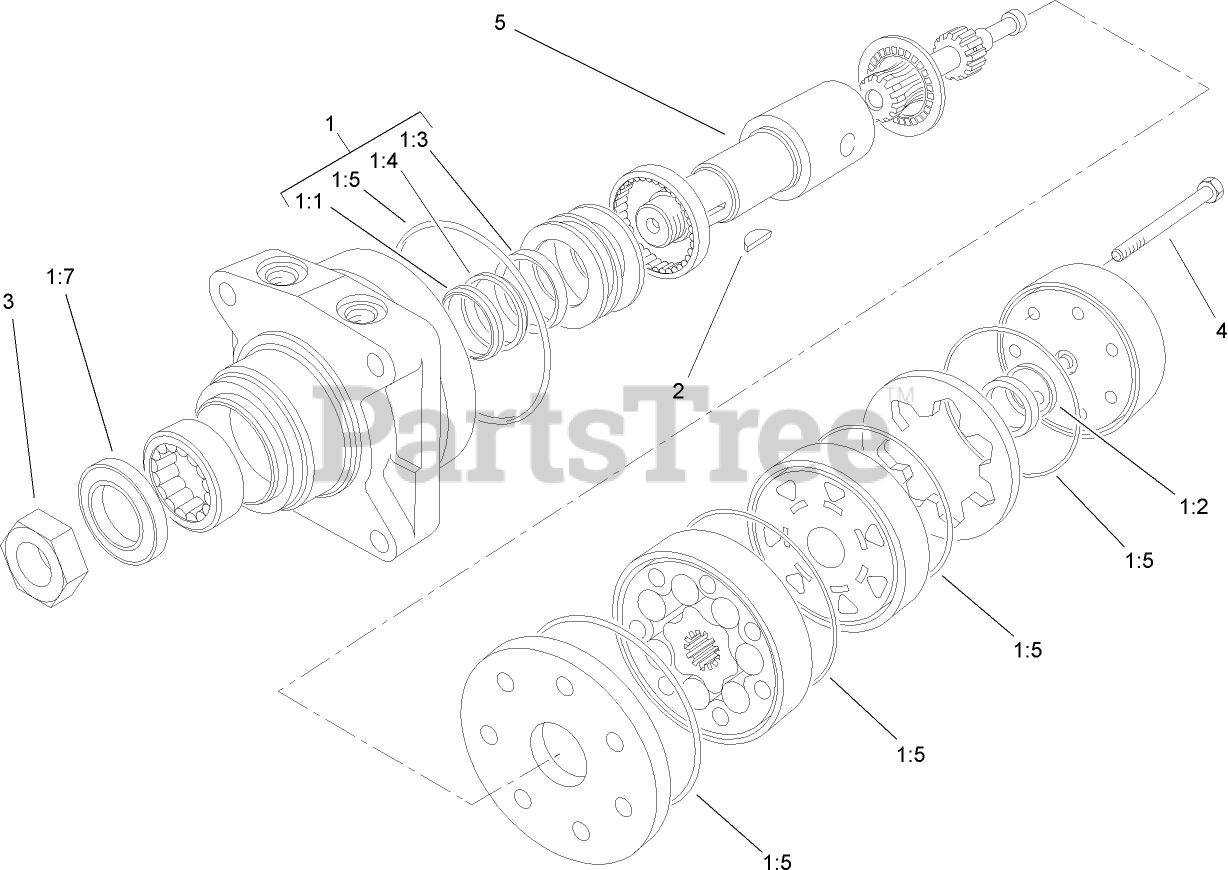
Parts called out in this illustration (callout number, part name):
1	SEAL KIT
1:1	Ring-Back Up
1:2	Seal-Commutator
1:3	SEAL-SHAFT (VITON)
1:4	WASHER-BACK UP, STEEL
1:5	RING-SEAL (VITON)
1:7	SEAL-DIRT AND WATER
2	KEY-WOODRUFF
3	NUT-MOTOR, WHEEL
4	BOLT-SPECIAL
5	SHAFT-COUPLING
